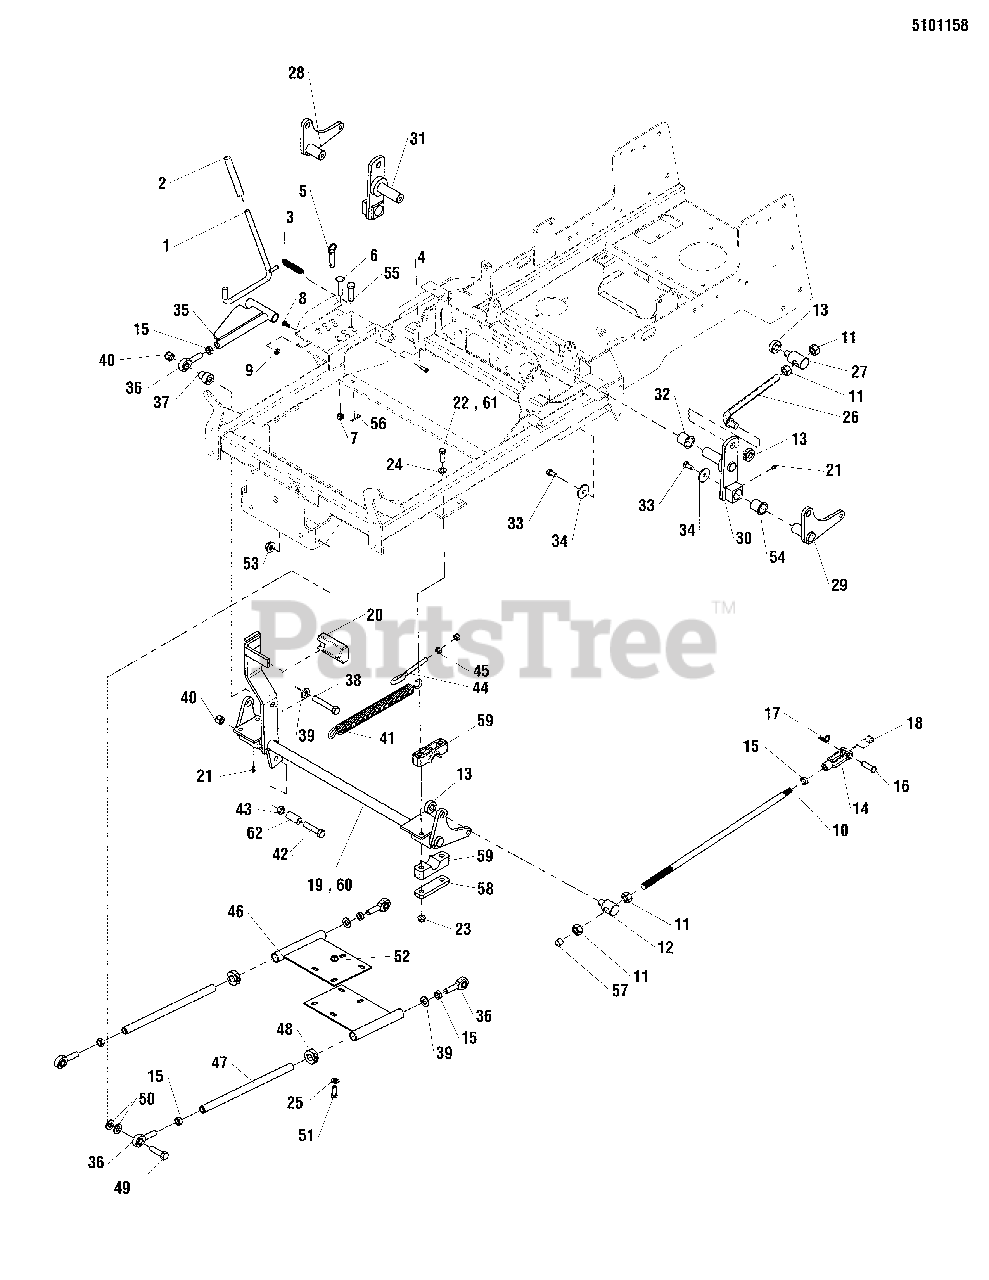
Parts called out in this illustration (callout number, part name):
1	WELD, ROD DECK LIFT - BLK
3	SPRING, EXTENSION
4	PIN, CLEVIS, 1/4 X 7/8
5	PIN, HITCH, 1/2 X 2.00 OAL, YP
6	BOLT, 3/8-16 X 2, CARRIAGE
7	NUT, 3/8-16 HEX SIDE LOCK
8	BOLT,1/4-20X5/8
9	NUT, 1/4-20 HEX SERR. FLANGE
10	ROD,DECK LIFT ADJUSTMENT
11	NUT, 5/8-11 HEX
12	PIVOT, SPRING ROD
13	COLLAR, 5/8" SPLIT
14	CLEVIS, 1/2-20, STEEL
15	NUT, 1/2-20 HEX JAM
16	PIN, CLEVIS, 1/2 X 1 1/2, YZP
17	PIN, HAIR, .0915 X 1-7/8
18	BUSHING, .510 X .625 X .500
19	WELD, DECK LIFT SHAFT - IS500-ORG
20	RUBBER, FOOT PEDAL
21	GREASE FITTING, 1/4-28 STRAIGHT
22	BOLT, 3/8-16 X 1-1/4 GD5
23	NUT, 3/8-16 HEX NYLOCK FLANGE
24	WASHER, 3/8 GD.9 FLAT
25	WASHER, 3/8 SAE
26	ROD, DECK LIFT
27	PIVOT, SPRING ROD
28	WELD, DECK HANGER-REAR-RH-BLK
29	WELD, DECK HANGER-REAR-LH-BLK
30	WELD, REAR LIFT, LH, IS500-BLK
31	WELD, REAR LIFT, RH, IS500-BLK
32	BUSHING, 1.00X1.13X.75, PLA
33	BOLT, 3/8-16 X 3/4, GD5, YZ WITH PATCH
34	WASHER, .390 X 1.50 X .109, YZ
35	WELD, DECK ADJUST LINK
36	BALL JOINT, 1/2-20, MALE
37	ADAPTER, CASTER AXLE
38	BOLT, 1/2-13 X 3 GD5
39	WASHER, 1/2 SAE
40	NUT, 1/2-13 HEX NYLON LOCK
41	SPRING, DECK LIFT ASSIST
42	BOLT, 1/2-13 X 2-1/4" GD5 YZ
43	NUT, 1/2-13 HEX JAM
44	EYE BOLT, 3/8-16 X 6, 3.0 THRD, 1 EYE
45	NUT, 3/8-16 HEX
46	WELD, DECK STABILIZER
47	SHAFT, DECK STABILIZER
48	COLLAR, 3/4" SPLIT
49	BOLT, 1/2-20 X 1-3/4 GD5 YZ
50	WASHER, 1/2" SAE
51	BOLT, 3/8-16 X 1 GD5 YZ
52	NUT, 3/8-16 HEX SERRATED FLANGE
53	NUT, 1/2-20 HEX NYLON LOCK
54	BUSHING, 1.00 X 1.13 X 1.38, PLASTIC
55	PIN, CLEVIS, 1/2 X 2 YZP
56	PIN, COTTER, 1/8" X 1-1/4
57	CAP, VINYL - .562 X .750 - BLK
58	PLATE, PIVOT BLOCK SUPPORT - BLK
59	PIVOT BLOCK, PLASTIC
60	WELD, DECK LIFT SHAFT - IS500Z - ORG
61	BOLT, 3/8-16 X 2-3/4 GD5 YZ
62	HOSE, 1/2" PUSH-ON, 1.00"
